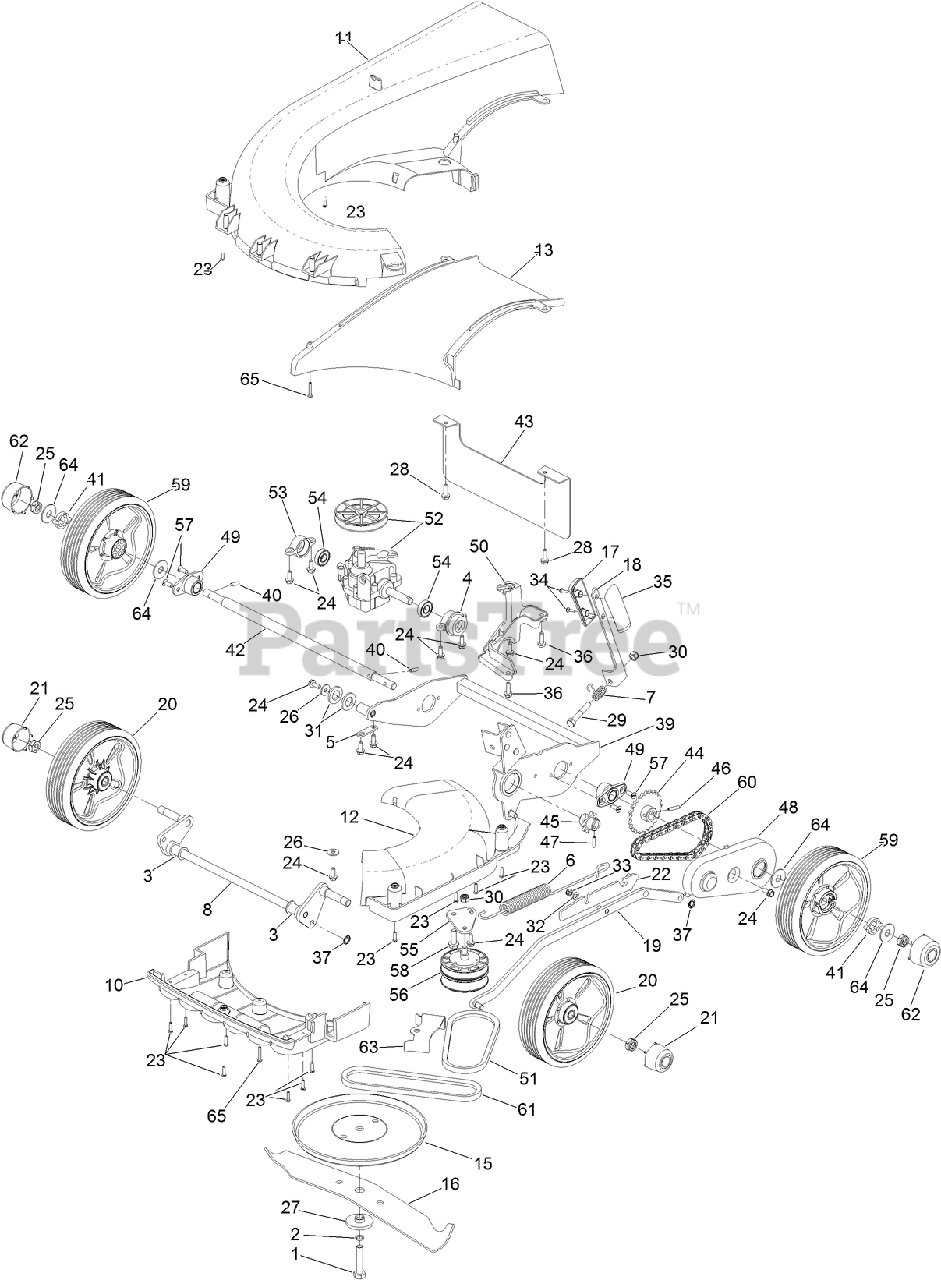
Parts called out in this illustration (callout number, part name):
1	BOLT-UNF
2	WASHER-SPRING
3	BEARING-AXLE, FRONT
4	HOUSING-PIVOT BEARING, LH
5	PLATE-SECURING
6	SPRING-COUNTER BALANCE
7	SPRING-HOC
8	AXLE-FRONT
10	MOULDING-FIN
11	MOULDING-SNAIL DECK
12	MOULDING-ACCESS, SNAIL DECK
13	MOULDING-THROW PLATE
15	DISC-FRICTION
16	CUTTERBAR
17	KNOB-HOC, RH
18	LEVER-HOC
19	ROD-CONNECTING BAR
20	WHEEL ASM
21	CAP-WHEEL, CENTER
22	MOUNT-SPRING
24	SCREW-TAPTITE
25	NUT-NYLOC
26	WASHER
27	SPACER-DISTANCE, CUTTERBAR
28	SCREW-TAPTITE
30	NUT-HEX, NI
31	WASHER-PLAIN
32	WASHER-PLAIN
33	NUT-NYLOC
35	KNOB-HOC, LH
36	SCREW-HH
37	WASHER-STARLOCK
39	FRAME-REAR WHEEL
40	KEY-DRIVE
41	CAM-DRIVE
42	AXLE-REAR
43	GUARD-REAR
44	SPROCKET-24T
45	SPROCKET-GEARBOX
46	PIN-SPRING, SELLOC
47	PIN-ROLL
48	COVER-DRIVE
49	HOUSING-BEARING, ROLLER
50	MOUNT-BEARING
51	BELT-VARIATOR
52	GEARBOX ASM
53	HOUSING-GEARBOX, BEARING (RH)
55	BRACKET-BELT
56	PULLEY VARIATOR ASM
57	SCREW-TAPTITE
58	SCREW-TAPTITE
59	WHEEL ASSEMBLY (DRIVE, GREY)
60	CHAIN-43 LINKS
61	BELT-VARIATOR (536)
62	CAP-DRIVE WHEEL
63	GUARD-BELT
64	WASHER-THRUST
